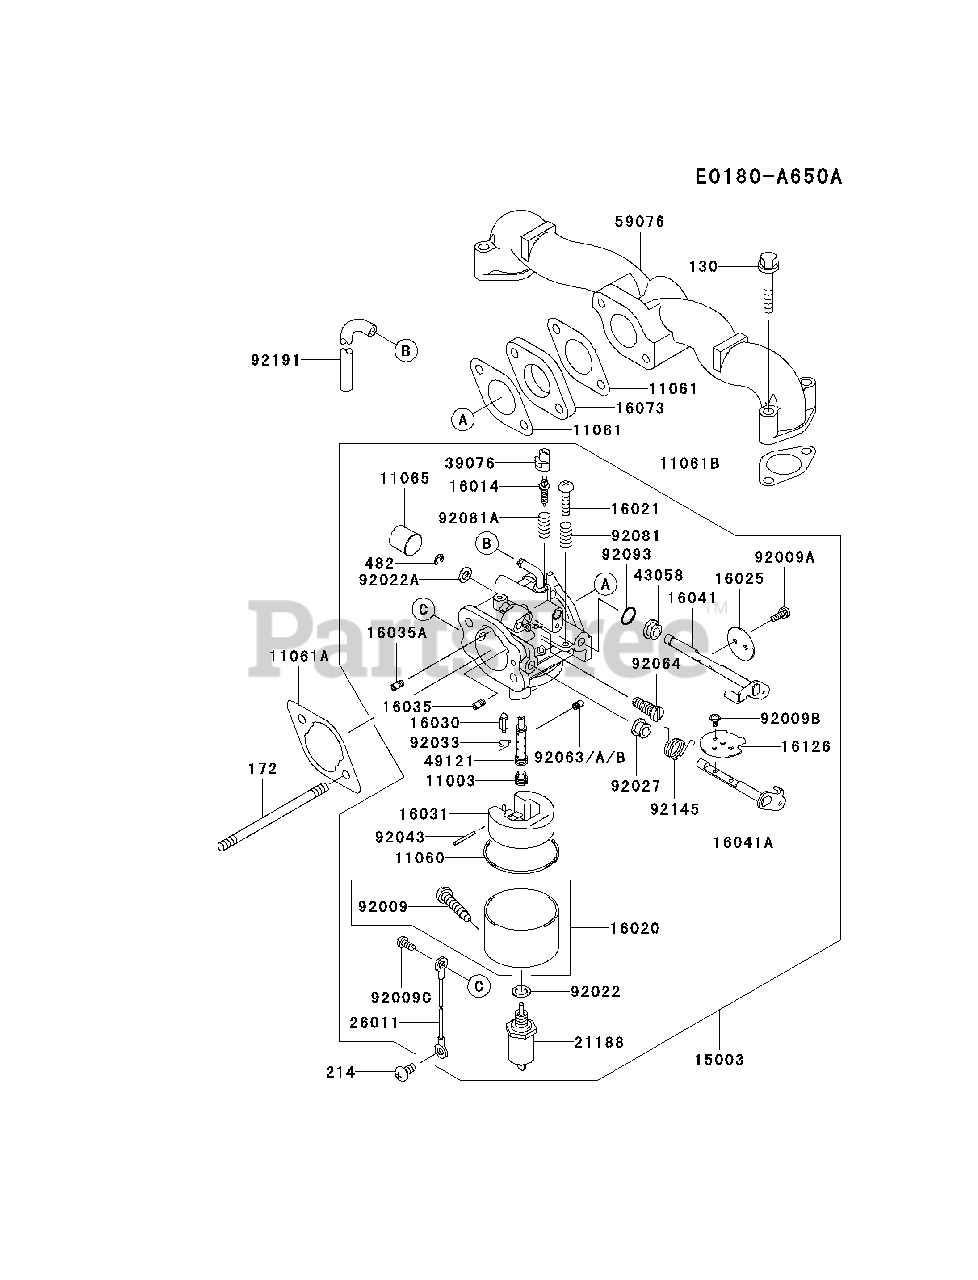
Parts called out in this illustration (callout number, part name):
130	BOLT-FLANGED
172	BOLT-STUD
214	SCREW-PAN+-
482	CIRCLIP-TYPE-E
92191	TUBE,4.76X7.94X225
